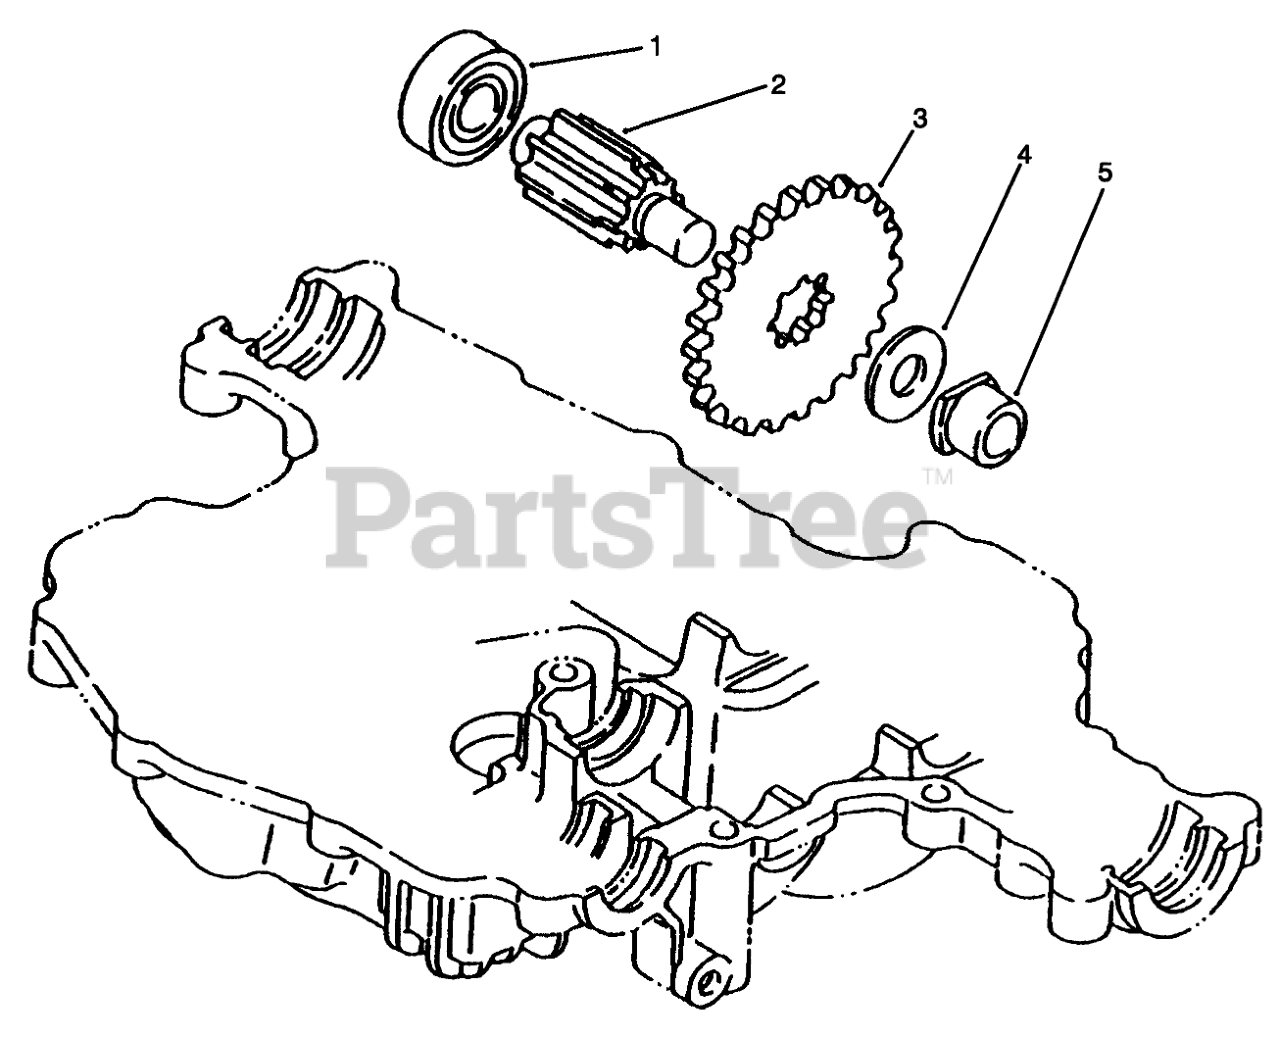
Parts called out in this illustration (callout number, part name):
1	BEARING
2	SHAFT - FINAL PINION
3	GEAR-FINAL SHAFT
4	WASHER
5	BUSHING
